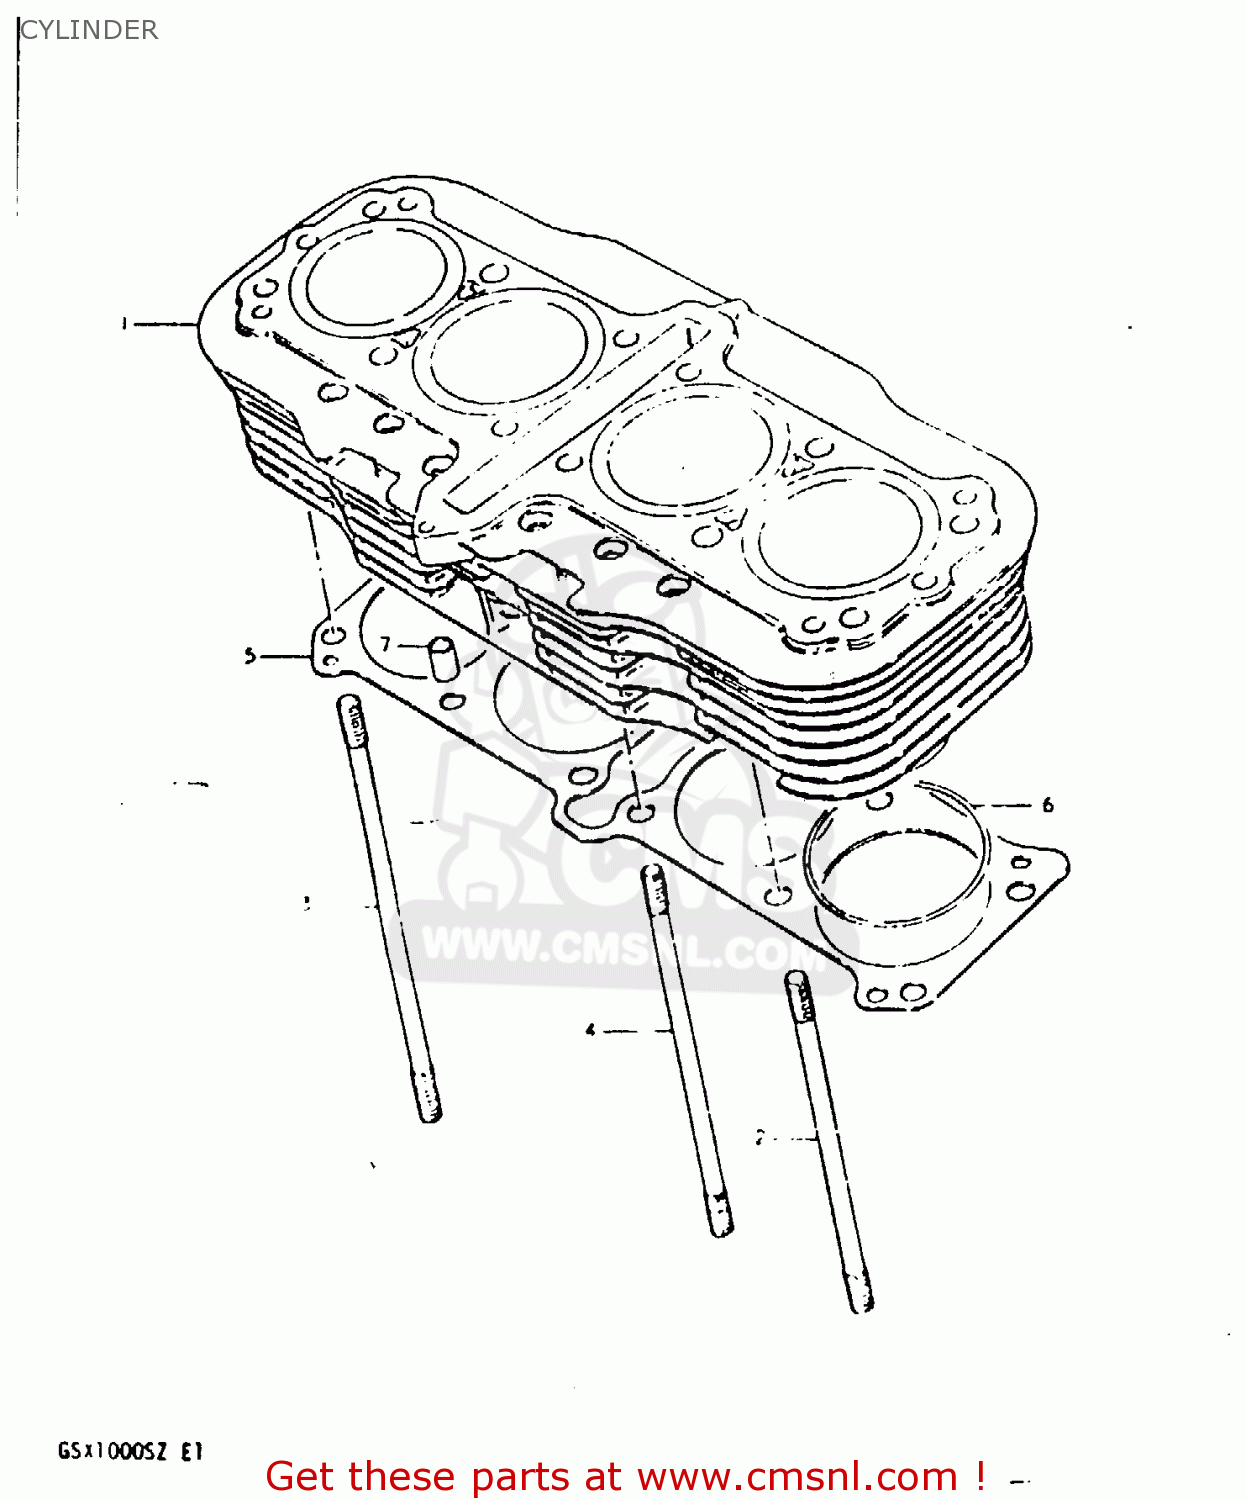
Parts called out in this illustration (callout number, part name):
1	CYLINDER
2	BOLT,STUD
3	STUD
4	BOLT,STUD
5	GASKET (MCA)
6	O RING(D:2,ID:74)
7	PIN
